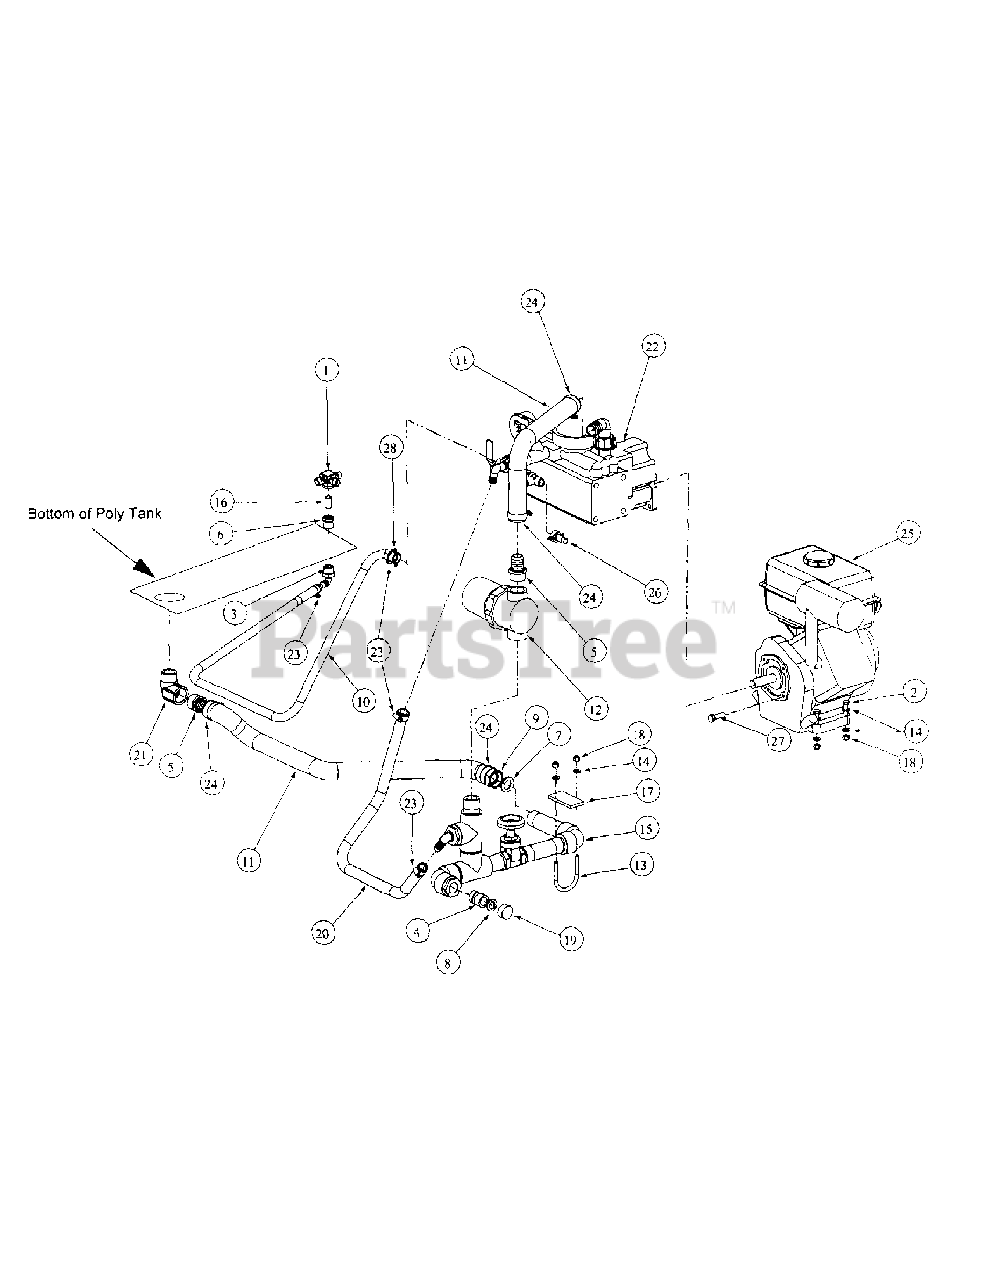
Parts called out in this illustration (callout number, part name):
1	Agitator, Jet
2	HHCS, 5/16-18, 1-3/4
3	Hose Barb, 1/2 NPT, 1/2 Nylon
4	Adapter, 3/4 NPT, 3/4 Hose
5	Hose Barb, 1" NPT, 1" Nylon
6	Adapter, 1/4 NPT, 1/2 NPT
7	Washer, Hose 1"
8	Washer Hose, 3/4" Rubber
9	Repair Coupling, Hose
10	Hose, 1/2" sold by the ft.
11	Hose, 1", Spiraflex sold by the ft.
12	Strainer, 30 Mesh-SS
13	U-Bolt, 5/16-18 x 2
14	Flat Washer, 5/16 SAE
15	Manifold Assembly
16	Nipple, 1/4 NPT
17	Rubber Pad 1/4" x 1-1/2" x 3"
18	Nut, 5/16-18, Nylock
19	Hose Cap, 3/4"
20	Hose 5/8" PVC sold by the ft.
21	Street Elbow, PVC 1" NPT x 1"
22	Pump Assembly
23	Hose Clamp, 1/2, 7/8
24	Hose Clamp, 7/8, 1-1/4
25	Engine, 5.5HP Kawasaki
26	Fittings
27	Button Head Bolt, m8-1.25 x 25 mm
